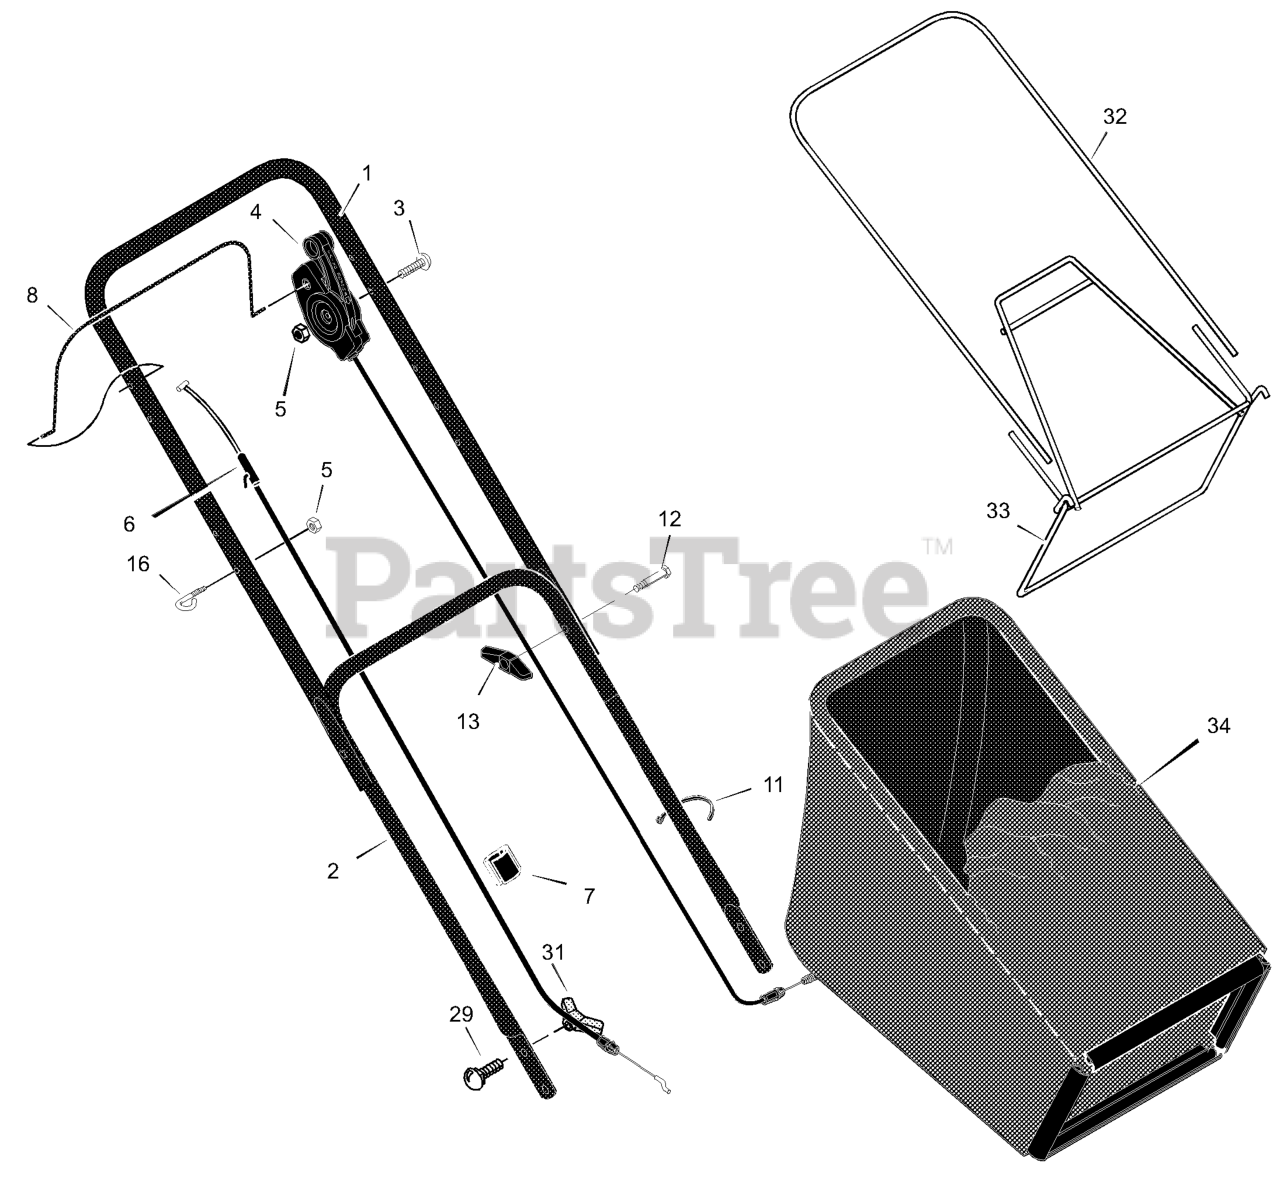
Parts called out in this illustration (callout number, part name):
1	Handle, Upper
2	Handle, Lower
4	Control, Drive
5	Locknut
6	Cable, Stop
7	Fastener, Cable
8	Lever, Stop
11	Fastener, Cable
13	Knob
16	Guide, Rope
29	Bolt, Carriage
31	Knob, Plastic
32	Tube, Bag
33	Frame Assembly
34	Bag, Cloth
